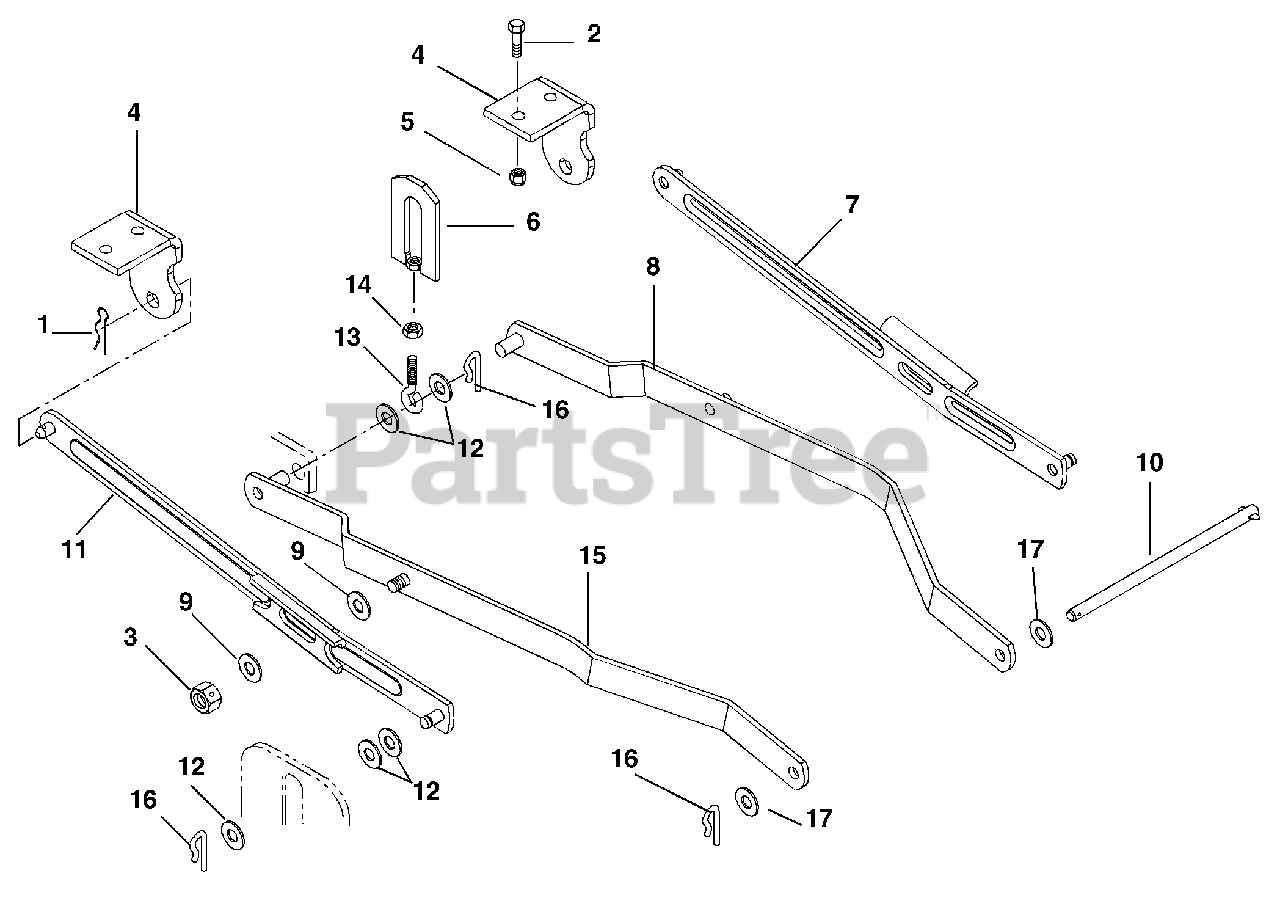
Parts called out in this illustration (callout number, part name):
1	PIN-HAIR-EXT .12X.31X2.37 YWZC
2	BLT-SERHFWH .38-16X.75 YWZC
3	@NUT-LK-CTR .62-11 YWZC
4	REAR HANGER
5	@NUT-LK-TOP-FLG .38-16 YWZC
6	LINK, ADJUSTMENT
7	HANGER, REAR LH
8	ARM, LIFT LH
9	@WSHR-FL-STL.656X1.31X.095 YWZ
11	HANGER, REAR RH
12	WSHR-FL-STL .531X1.250X.10 YWZ
13	BLT-EYE .375-16X2.50 YWZC
14	NUT-HEX-JAM .375-16 YWZC
15	ARM, LIFT RH
16	CLIP, SPRING
17	@WSHR-FL-STL.531X1.06X.095YWZC
